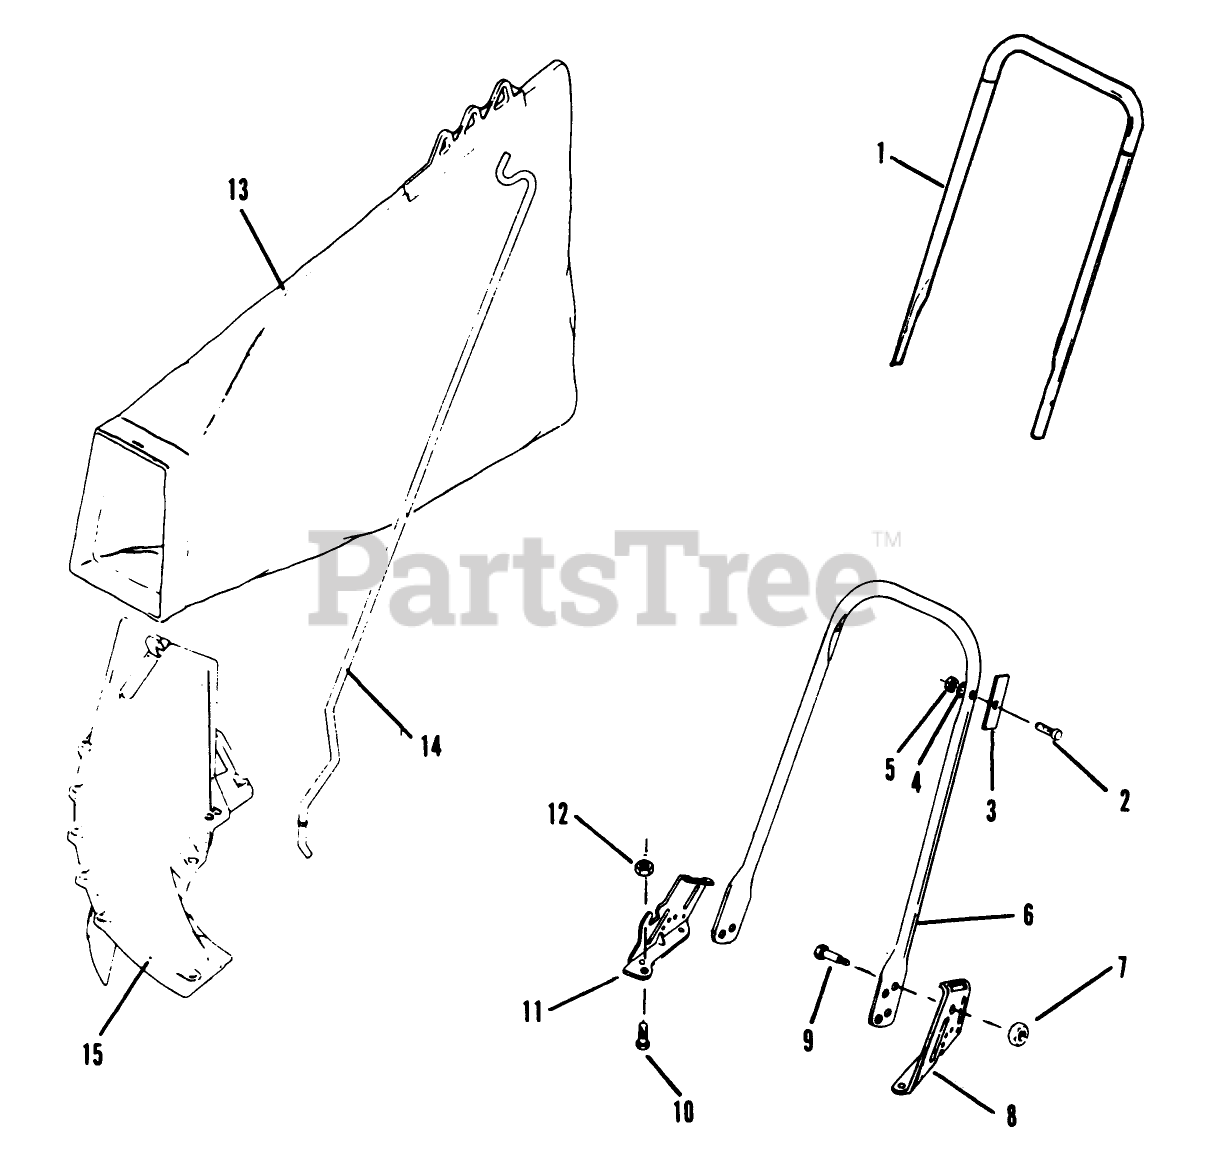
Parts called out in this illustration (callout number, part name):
4	WASHER-CURVED
5	LOCKNUT E
7	NUT-JAM, LOCKING
12	NUT-LOCK F
13	89802 LB WHOLE GOODS
14	ROD GRASSBAG
